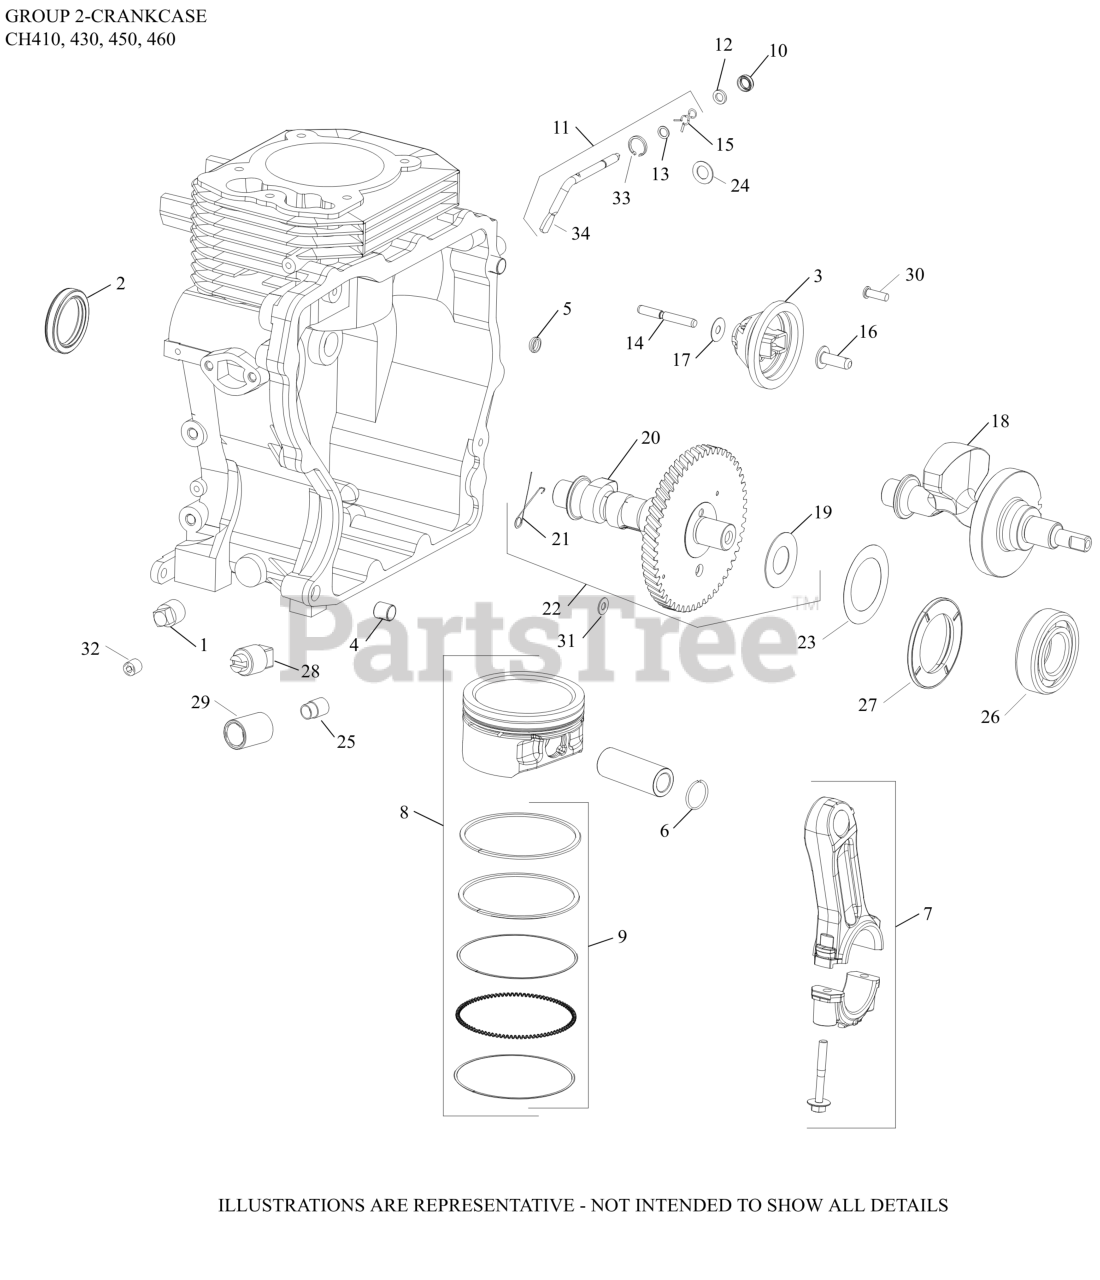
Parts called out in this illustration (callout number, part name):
1	PLUG, SQ HD PIPE 3/8"
2	SEAL, OIL
3	GOVERNOR GEAR ASSEMBLY
4	PIN, LOCATING
5	PLUG, CUP
7	ROD, CONNECTING (STD)
7	ROD, CONNECTING (.25)
8	KIT, PISTON W/RING SET (STD)-(#DSC)
8	KIT, PISTON W/RING SET (.25)-DISC.
8	KIT, PISTON W/RING SET (.50)-DISC.
8	KIT, PISTON W/RING SET (.08)-DISC.
9	RING SET (STD & .08)
11	KIT, GOVERNOR CROSS SHAFT
12	WASHER, FLAT 6 MM
14	SHAFT, GOVERNOR GEAR
16	PIN, GOVERNOR REGULATING
17	WASHER, FLAT 6 MM
18	SHAFT, BALANCE
19	SHIM, CAMSHAFT (WHITE .028")
19	SHIM, CAMSHAFT (BLUE .03")
19	SHIM, CAMSHAFT (RED .032")
19	SHIM, CAMSHAFT (YELLOW .034")
19	SHIM, CAMSHAFT (GREEN .036")
19	SHIM, CAMSHAFT (GRAY .038")
19	SHIM, CAMSHAFT (BLACK .04")
20	KIT, CAMSHAFT ASSEMBLY-DISCONTINUED
21	SPRING, ACTUATING
34	SHAFT, GOVERNOR CROSS
NI	KIT, ROD BOLTS
